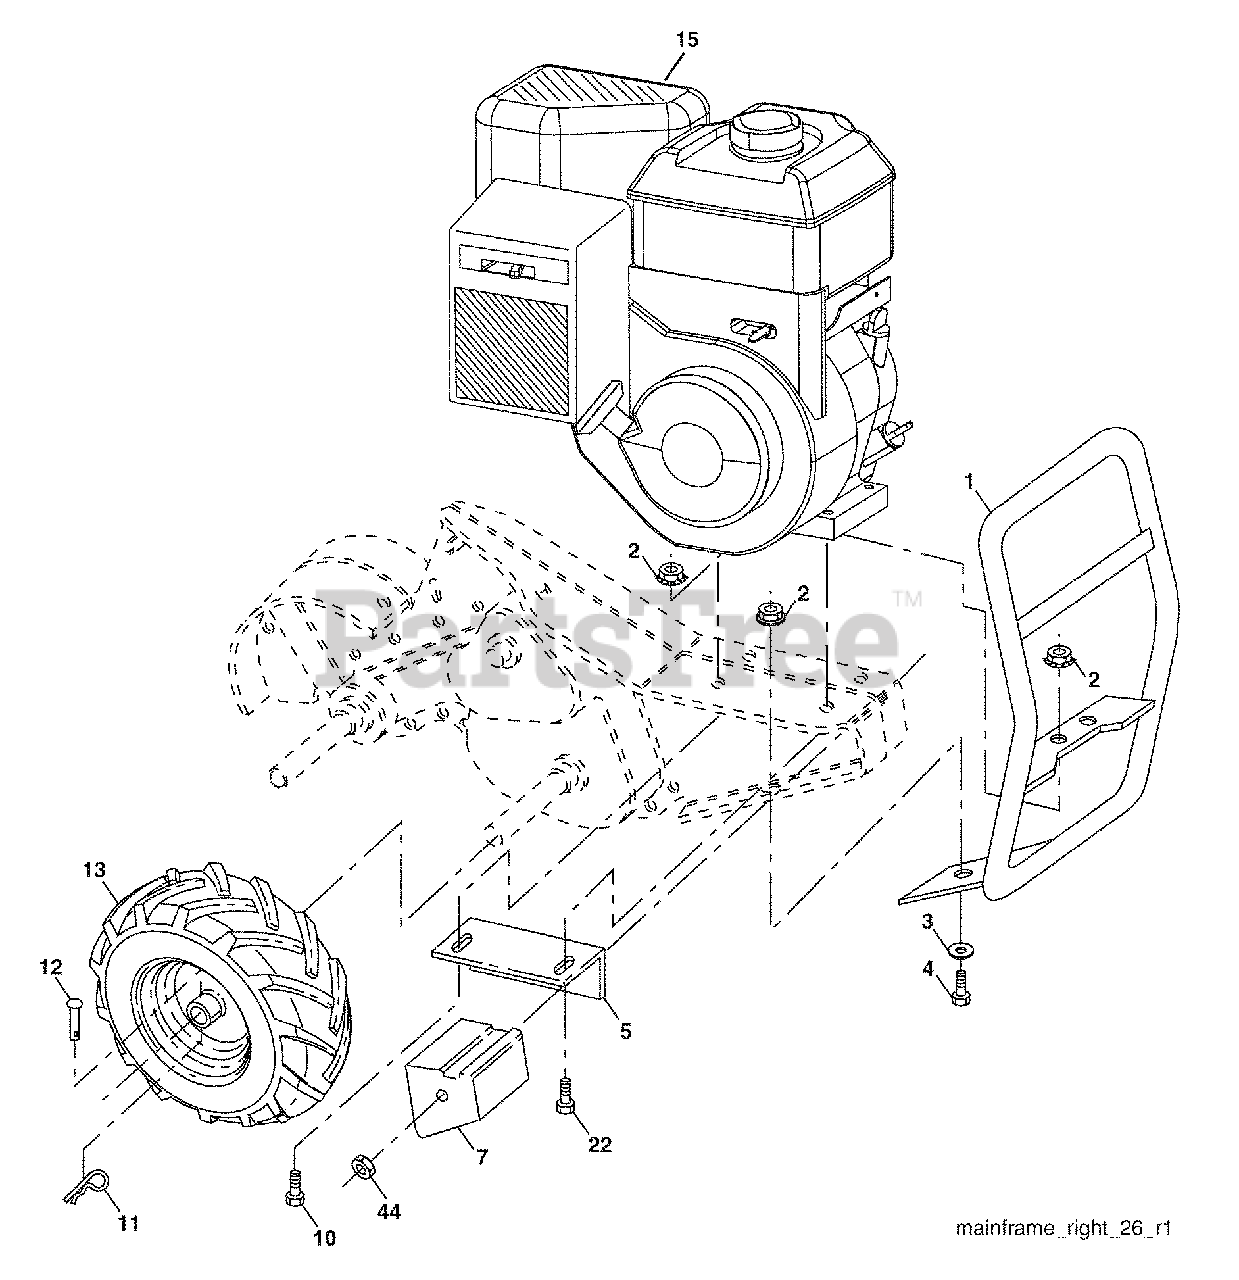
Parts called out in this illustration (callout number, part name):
1	Bumper Asm.
2	Locknut, Hex, Flange 5/16-
3	Washer 11/32 x 11/16 x 16
4	Bolt 5/16-18 x 3/4
5	Bracket, Reinforcement
7	Counter Weight, RH
10	Bolt, Hex 5/16-18 x 1-1/2
11	Clip, Hairpin
12	Rivet, Drilled
22	Bolt 5/16-18 x 1-3/4
44	Nut, Keps, Hex 3/8-16 unc
